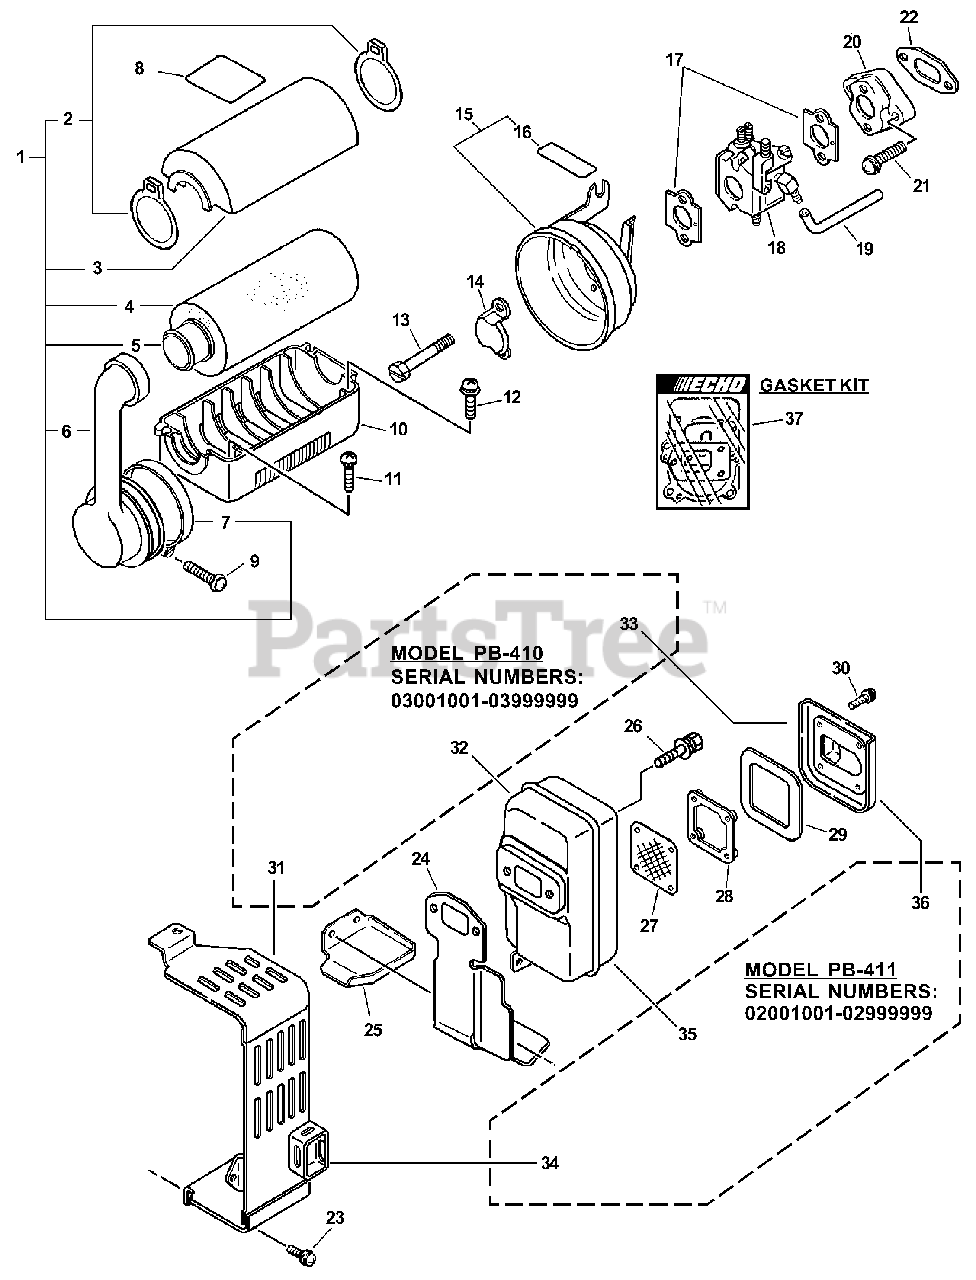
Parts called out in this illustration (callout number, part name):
1	AIR CLEANER ASSY
3	COVER, AIR FILTER
4	FILTER, AIR
5	FILTER, AIR
6	ADAPTOR, INTAKE
8	LABEL - CAUTION
9	SCREW - 5X30
10	CASE, AIR FILTER
11	SCREW - 6X15
12	SCREW - 6X20
13	SCREW - 5X55
14	PLATE, PREVENT
15	CASE, AIR FILTER
16	LABEL - CHOKE
17	GASKET, INTAKE
18	CARBURETOR WT-410C
19	PIPE - IMPULSE
20	INSULATOR, INTAKE
21	SCREW - 6X25
22	GASKET, INTAKE
23	SCREW - 5X14
24	GASKET, EXHAUST
25	BRACKET, MUFFLER COVER
26	SCREW - 6X20
27	SCREEN, SPARK ARRESTOR
28	RETAINER, SCREEN
29	GASKET, EXHAUST
30	SCREW - 4X16
31	COVER, EXHAUST
33	GUIDE, EXHAUST
34	SHIELD, EXHAUST
35	MUFFLER
36	GUIDE, EXHAUST
37	GASKET KIT
